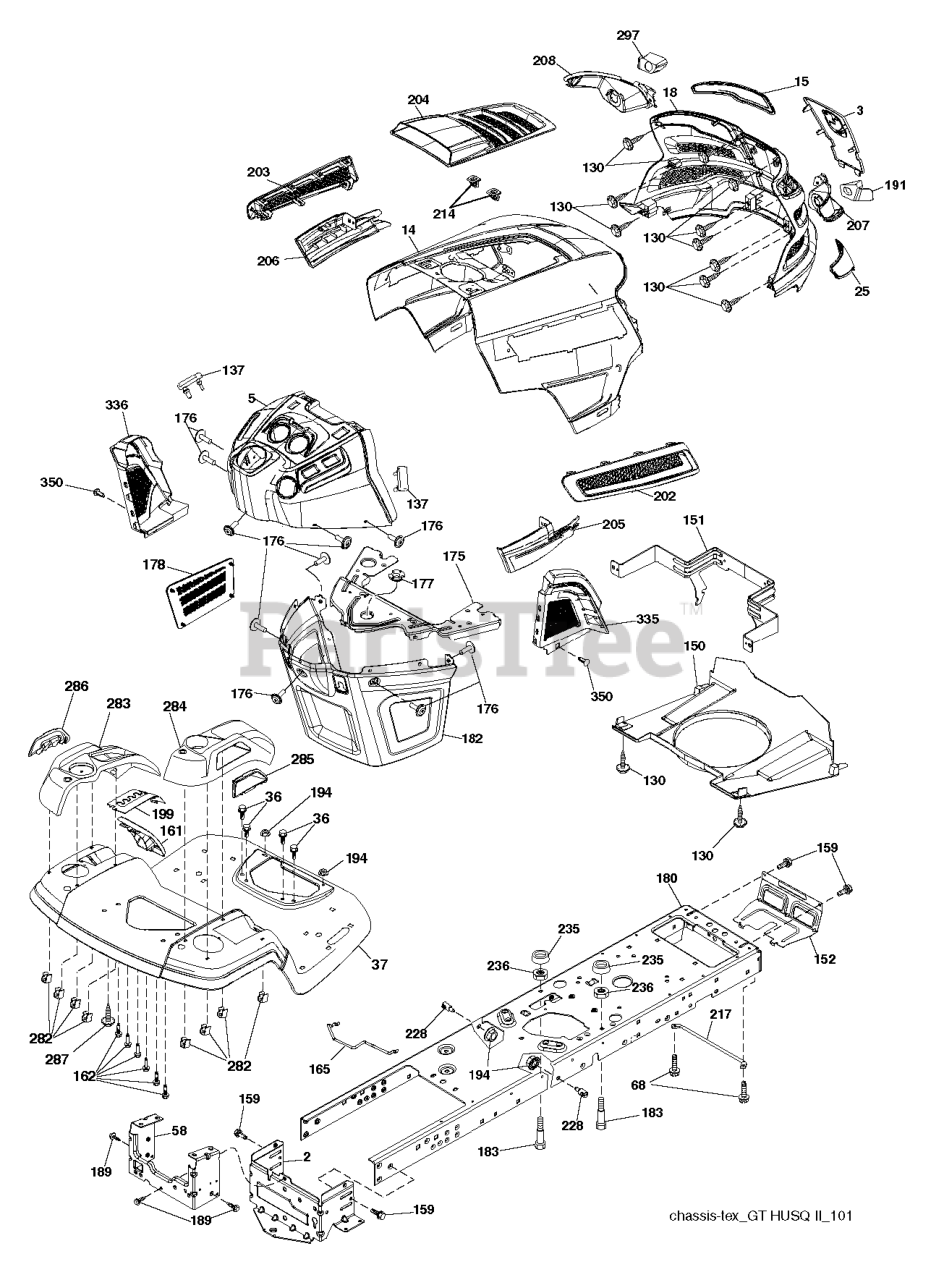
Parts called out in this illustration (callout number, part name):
2	DRAWBAR.LOWER.2PC.18/22
3	APPLIQUE.SUBASM.GT.HUSQ.II
5	DASH.UPPER.ASSY.GT2.DUAL
14	HOOD.ASM.HUSQVARNA.GT.TEX.ORAN
15	LENS.HEADLIGHT.LH.GTII.2011
18	GRILLE.SUBASM.GT.HUSQ.II
25	LENS.HEADLIGHT.RH.GTII.2011
36	SCREW 5/16"
37	FENDER.TLT.FS.W/CPH/FW/RSF.668
58	DRAWBAR UPPER 2PC SMALL FENDER
68	Screw 5/16-18 x 1/2 Hex, Self Tapping 5/16-18 x 1/2
130	SCREW.#10 X 0.750.BOS
137	BUMPER DASH
150	AIR.DUCT.GTV.BLACK
151	BRACKET.PIVOT.HOOD.GT.HUSQ.II
152	SHIELD.BROWNING.PNT.GT.V2
159	SCREW, 3/8-16X3/4
161	WINDOW.FUEL.LT.HUSQ.TEX.498
162	SCREW.HI-LO.CONSOLE
165	SUPPORT.TANK.REAR.B/TE
175	PLATE.CROSSMEMBER.HUSQ
176	SCREW.#10-24X5/8.RN.QU
177	BUSHING, STEERING
178	CARGO.ASM.NET.TXGT.W/C
180	CHASSIS.STAMPING.LT/GT
182	DASH.LOWER.COMMON.12V.ADAPTOR
183	BOLT.5/16-18X1-1/4 FULL THD
189	SCREW
191	INSERT.REFLECTIVE.RH.HUSQ.GTII
194	NUT LOCK HEX FLANGE 5/16-18
199	PLATE.DECK.LIFT.HUSQ.LT
202	VENT.SIDE.RH.GT.HUSQ.II.
203	VENT.SIDE.LH.GT.HUSQ.II.498
204	VENT.TOP.HUSQ.GT2
205	SIDE.TRIM.RH.GT.HUSQ.II
206	SIDE.TRIM.LH.GT.HUSQ.II.GRAY
207	BEZEL LIGHT.RH.GT.II.MYLAR
208	BEZEL LIGHT.LH.GT.II.MYLAR
214	CLIP.RETAINER.TINNER.
217	ROD.PIVOT.HOOD
228	STUD.FASTNER.W/ANTI-ROTATE
235	SPACER FENDER
236	NUT.CENTERLOCK.5/16-
282	CLIP.RETAINER.CONSOLE.LT.HUSQ
283	CONSOLE.DECK.LIFT.R.SDFL.HUSQ
284	CONSOLE.SHFT.PDL.CNTRL.HUSQ.LT
285	CONSOLE INSERT RH
286	CONSOLE.INSRT.LH.HUSQ.LT.BLACK
287	SCREW 1/4X20
297	INSERT.REFLECTIVE.LH.HUSQ.GTII
335	COVER.LOWER.DASH.RH.BLACK
336	COVER-LH.LOWER.DASH.GT2.BLACK
350	CLIP.X-MAS.TREE
